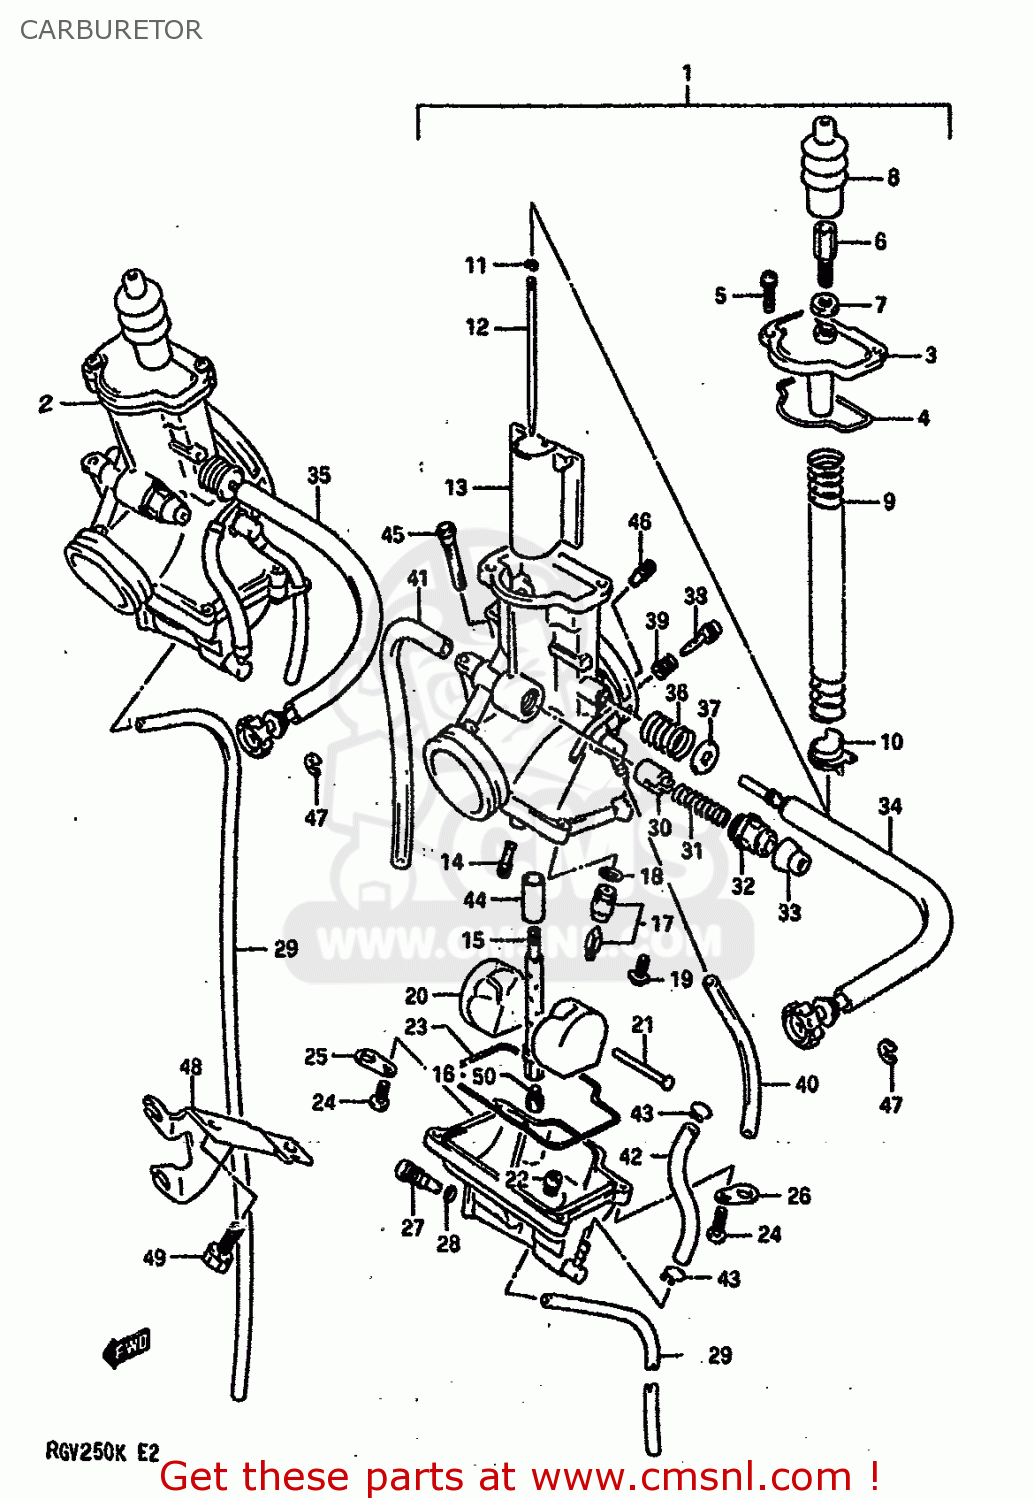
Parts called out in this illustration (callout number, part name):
1	CARBURETOR ASSY,LH
2	CARBURETOR ASSY,RH
3	CAP, TOP
4	O RING,TOP CAP
5	SCREW
6	ADJUSTER,CABLE
7	NUT
8	CAP,CABLE ADJUSTER
9	SPRING
10	RING
11	CLIP,NEEDLE
12	NEEDLE,JET
13	VALVE,PISTON(CA:1.5)
14	JET,PILOT(25)
15	JET,NEEDLE(O-6)
16	JET,MAIN(200)
17	VALVE ASSY,NEEDLE
18	O-RING,NEEDLE VALVE
19	SCREW
20	FLOAT
21	PIN,FLOAT
22	JET
23	GASKET,FLOAT CAHMBER (NAS)
24	SCREW
25	PLATE,CARBURETOR
26	PLATE
27	PLUG,DRAIN
28	O RING
29	HOSE (3X5X525)
30	PLUNGER,STARTER
31	SPRING
32	HOLDER,GUIDE
33	CAP
34	ADJUSTER,THROTTLE STOP
35	ADJUSTER,THROTTLE STOP
36	SPRING
37	WASHER
38	SCREW
39	SPRING
40	HOSE(3X5X650)
41	HOSE
42	HOSE SET
43	CLIP
44	RING
45	FILTER
46	JET,MAIN AIR(0.7)
47	E RING
48	BRACKET,ADJUSTER
49	BOLT
50	JET
